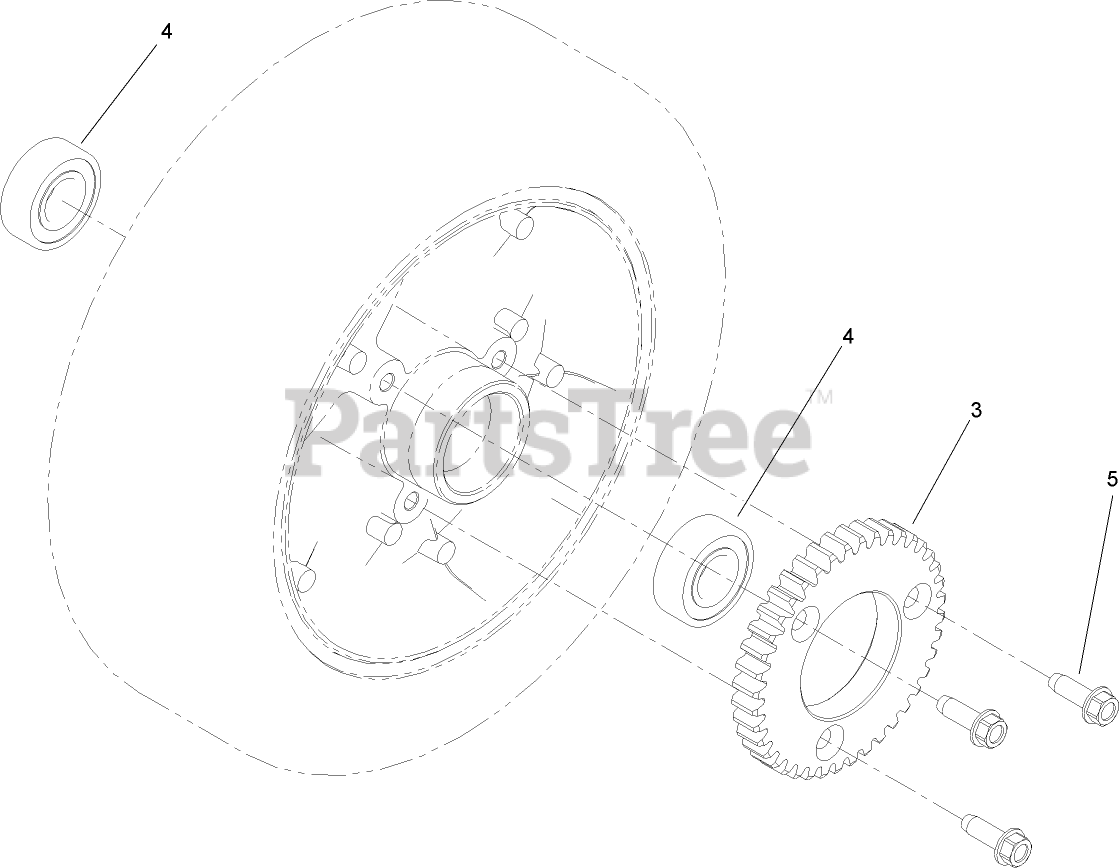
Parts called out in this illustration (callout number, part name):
3	GEAR-DRIVEN
4	BEARING-BALL
5	SCREW-HWHTF
